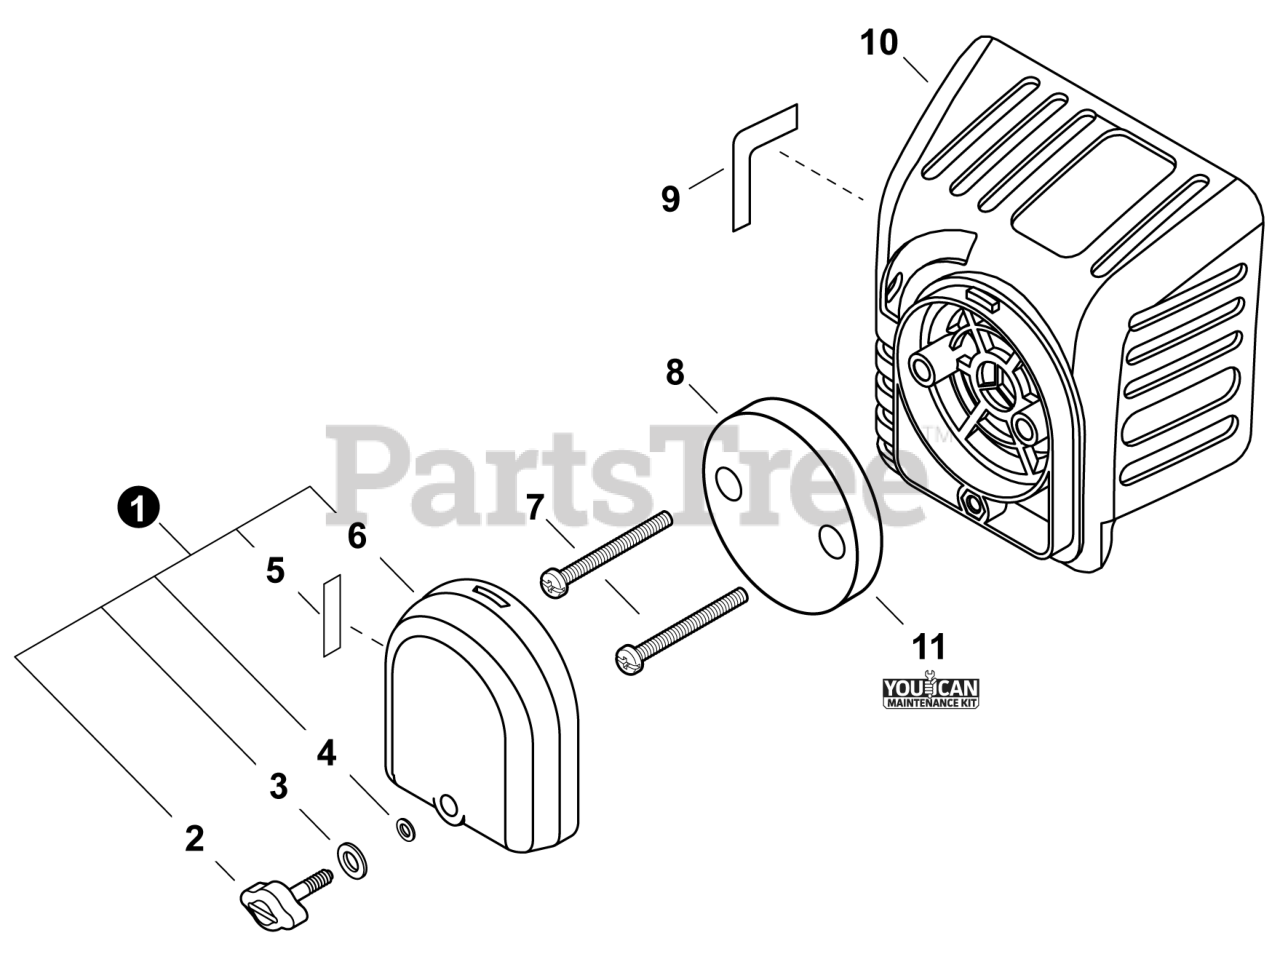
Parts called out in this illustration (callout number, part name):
1	COVER ASSY, AIR FILTER
2	THUMBSCREW
3	WASHER, CONE M6
5	LABEL - CHOKE
6	COVER, AIR FILTER
7	SCREW M4×25
8	FILTER, AIR
9	LABEL - CARBURETOR
10	CASE, AIR FILTER
11	TUNE-UP KIT - YOUCANT
